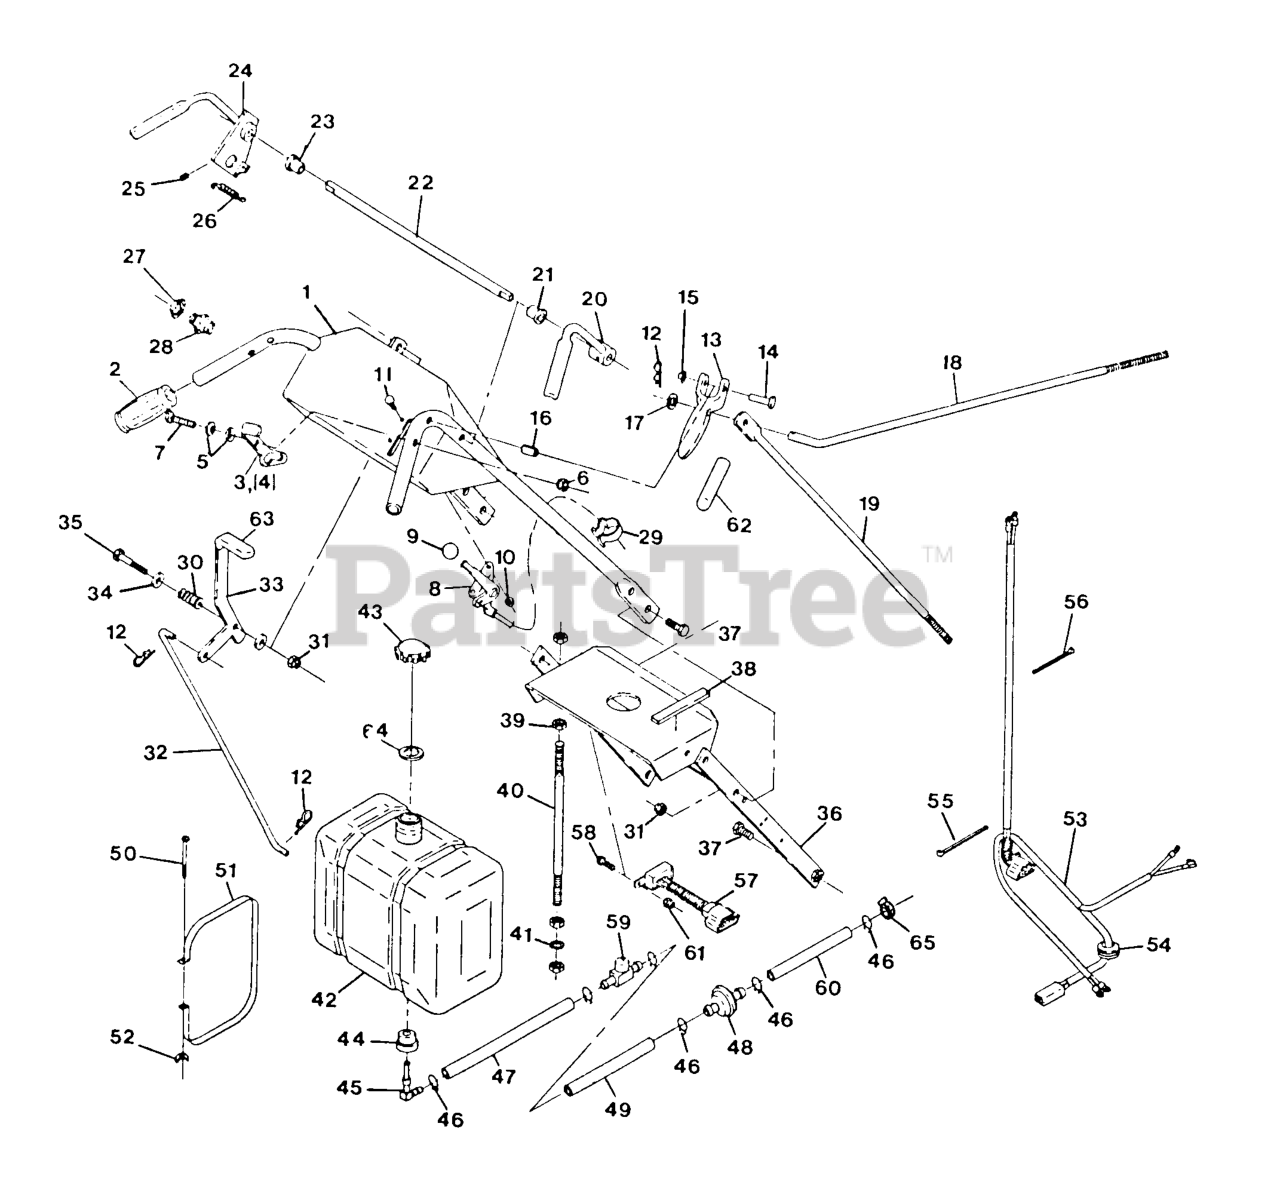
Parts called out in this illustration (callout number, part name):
3	LATCH,W/GRIP RH
4	LATCH,W/GRIP LH
5	WASHER-SPRING
8	CABLE,THROTTLE CONTROL
9	KNOB-BALL
11	BOLT-CARR
12	PIN-COTTER
13	DRIVE LEVER ASM
14	PIN-LEVER, DRIVE
15	NUT-PUSH
16	PIN-ROLL
18	LINKAGE,BRAKE
19	LINKAGE,CALIPER
21	BUSHING-NYLON
22	ROD,CONNECTING
23	BUSHING,FLANGED
25	SCREW-SET
26	SPRING-EXTENSION
28	SWITCH,OPERATOR CNTRL
29	CLIP-CABLE
30	SPRING-COMPRESSION
32	LINKAGE-BLADE, UPPER
38	PAD,PLASTIC TANK
45	ELBOW-TANK, FUEL
47	FUEL LINE
50	SCRW,MACH CRPH
52	WINGNUT
54	GROMMET
55	TIE-PLASTIC
56	TIE-CABLE
59	VALVE-FUEL
62	GRIP-LEVER, DRIVE
63	GRIP-LEVER
64	GASKET-CAP, TANK
65	CLAMP-HOSE
